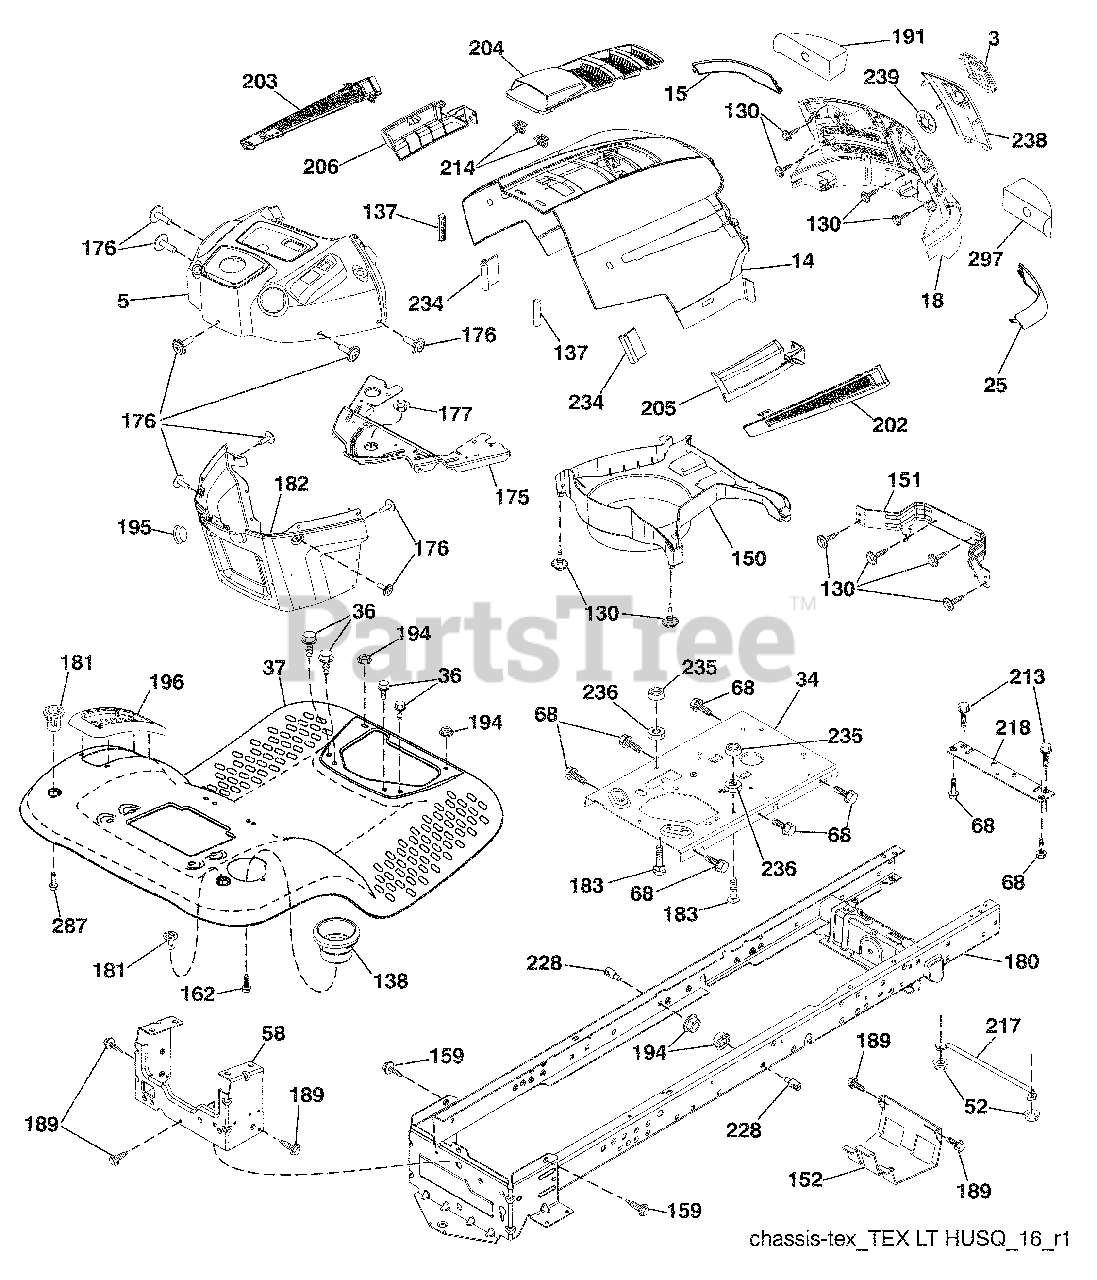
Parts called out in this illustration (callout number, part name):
3	Logo
5	Dash
14	Hood
15	Lens LH
18	Grille/Lens Asm.
25	Lens RH
34	Plate Engine
36	Screw 5/16-18 x 3/4
37	Fender
52	Nut Crown Lock 5/16
58	Drawbar Upper
68	Screw THDROL 5/16-18 x 1/2
130	Screw #10 x 0.750 BOS Thread
137	Bumper Dash
138	Cupholder
151	Bracket Pivot
152	Shield Browning
159	Screw Hexwash Thor 3/8-16 x 3/4
175	Crossmember
176	Screw 10-24 x 5/8
177	Bushing Steering
181	Bushing Mtg. Fender Crgo
182	Dash Lower
183	Bolt 5/16-18 unc x 1-1/4
189	Screw 5/16-18 x 3/4
191	Insert Reflective RH
194	Nut Lock Hex Flange 5/16-18
195	Plug Dash
196	Console Asm. Deck Lift
202	Vent Side Hood RH
203	Vent Side Hood LH
204	Vent Top Hood
205	Skirt Side RH
206	Skirt Side LH
213	Bolt 5/16-18 x 3/4
214	Clip Retainer
217	Rod Pivot Hood
218	X-Piece Hood Stop
228	Stud Fastener
234	Bumper Hood
235	Spacer Fender
236	Nut Lock 5/16-18 unc
238	Trim
239	Clip Tinnerman
287	Screw Hex Washead 1/4-20 x 3/8
297	Insert Reflective LH
